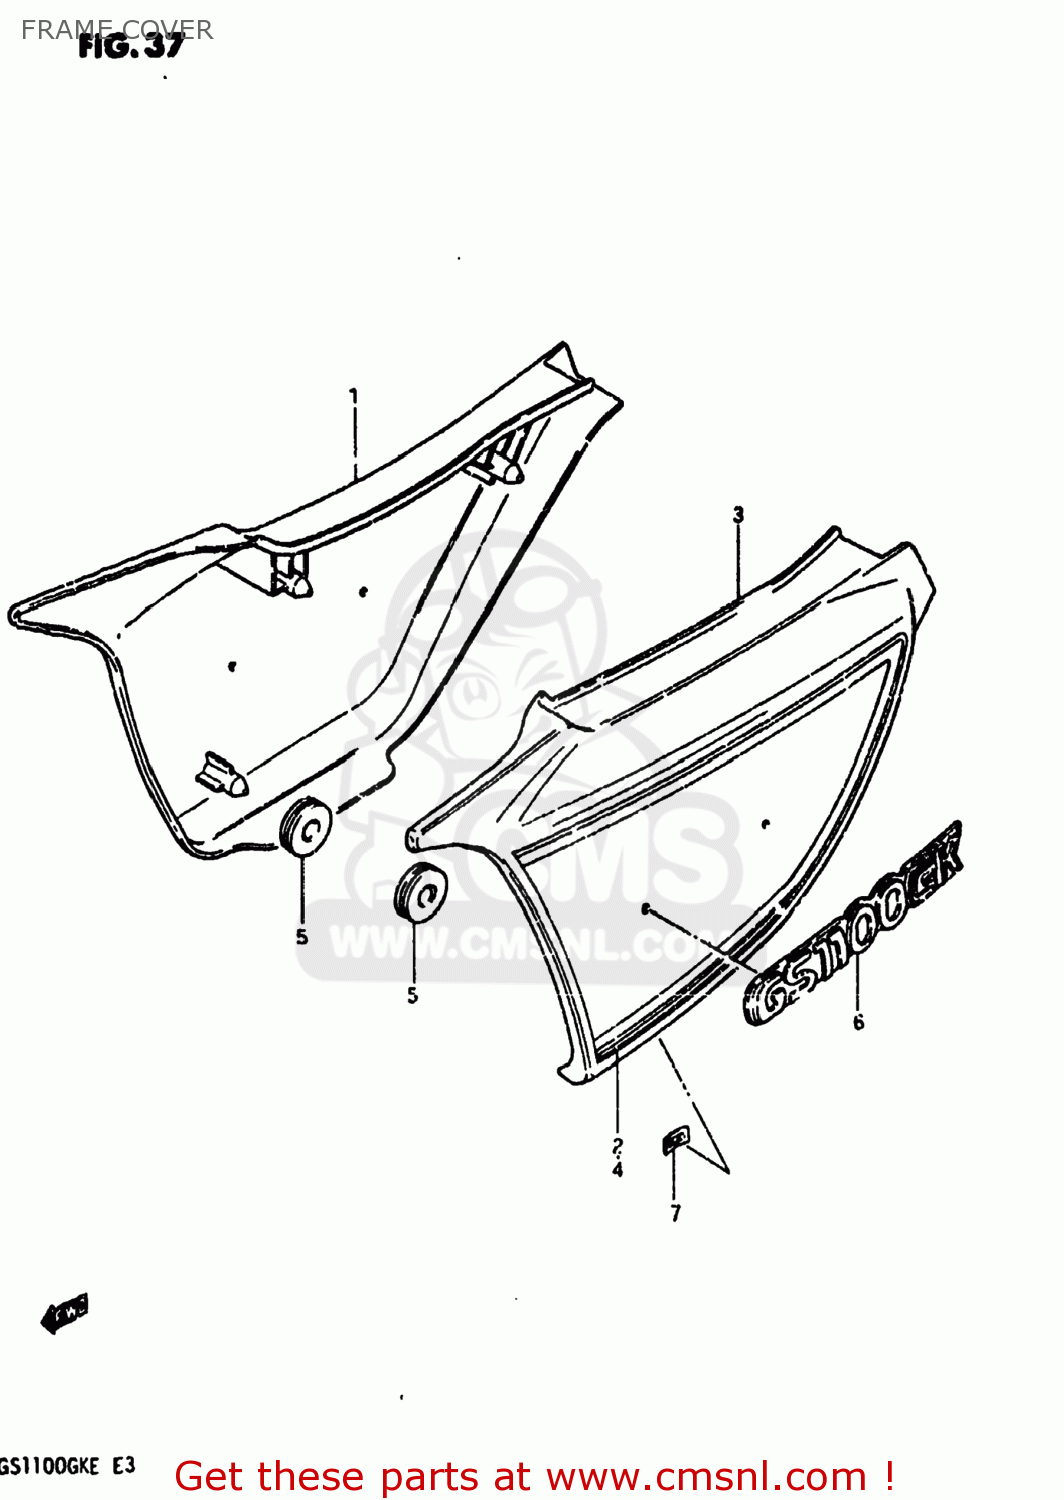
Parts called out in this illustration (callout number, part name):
1	COVER,FRAME,RIGHT
2	TAPE SET,FRAME COVER
3	COVER,FRAME,LEFT
4	TAPE SET,FRAME COVER
5	CUSHION
6	EMBLEM,FRAME COVER
7	NUT
